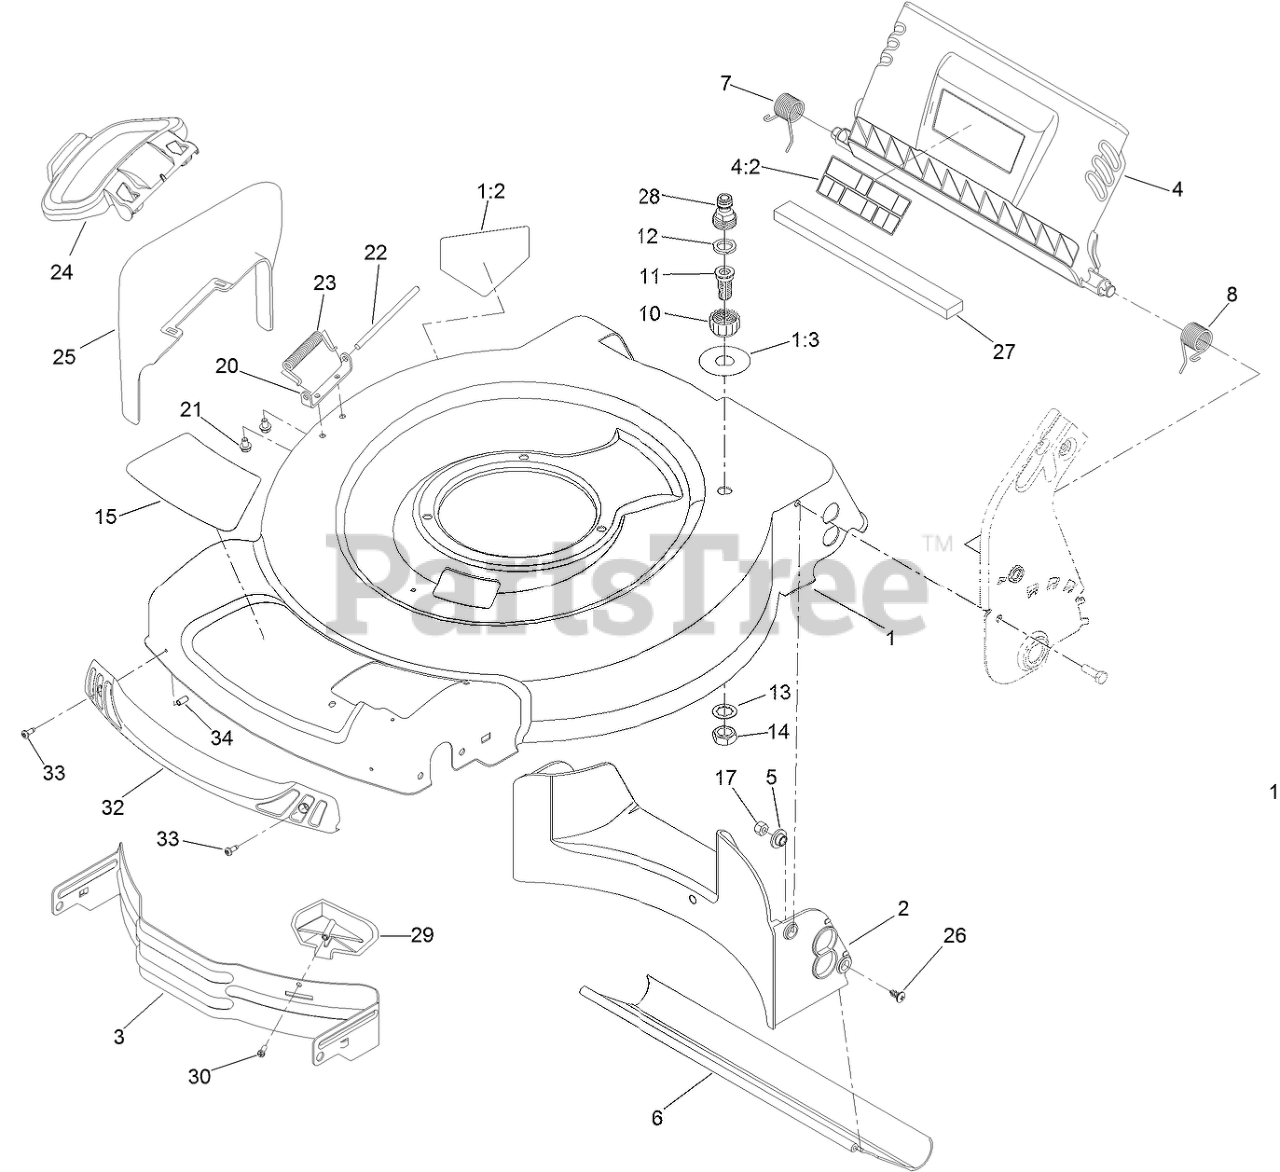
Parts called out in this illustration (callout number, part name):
1	HOUSING ASM
1:2	DECAL-DANGER
1:3	DECAL-PORT, WASHOUT
2	BAFFLE-REAR
3	BAFFLE-FRONT
4	REAR DEFLECTOR ASM
4:2	DECAL-WARNING
5	WASHER-STEPPED, BAFFLE
6	SHIELD-TRAILING
7	SPRING-TORSION
8	SPRING-TORSION
10	COUPLING-HOSE, WASHOUT PORT
11	PORT-WASHOUT
12	WASHER-SEAL, WASHOUT PORT
13	WASHER-TOOTH, INTERNAL
14	NUT-JAM
15	DECAL-DECK
17	NUT-LOCK, NI
20	BRACKET-COVER
21	SCREW-HWH
22	ROD-COVER
23	SPRING-TORSION
24	DEFLECTOR-SIDE
25	CHUTE-DISCHARGE, SIDE
26	SCREW-PTH
27	FOAM-SEAL
28	ADAPTER-CONNECT, QUICK
29	KICKER-FRONT
30	SCREW-PPH
32	BUMPER
33	SCREW-FORMING, THREAD
34	CAP-PLUG
